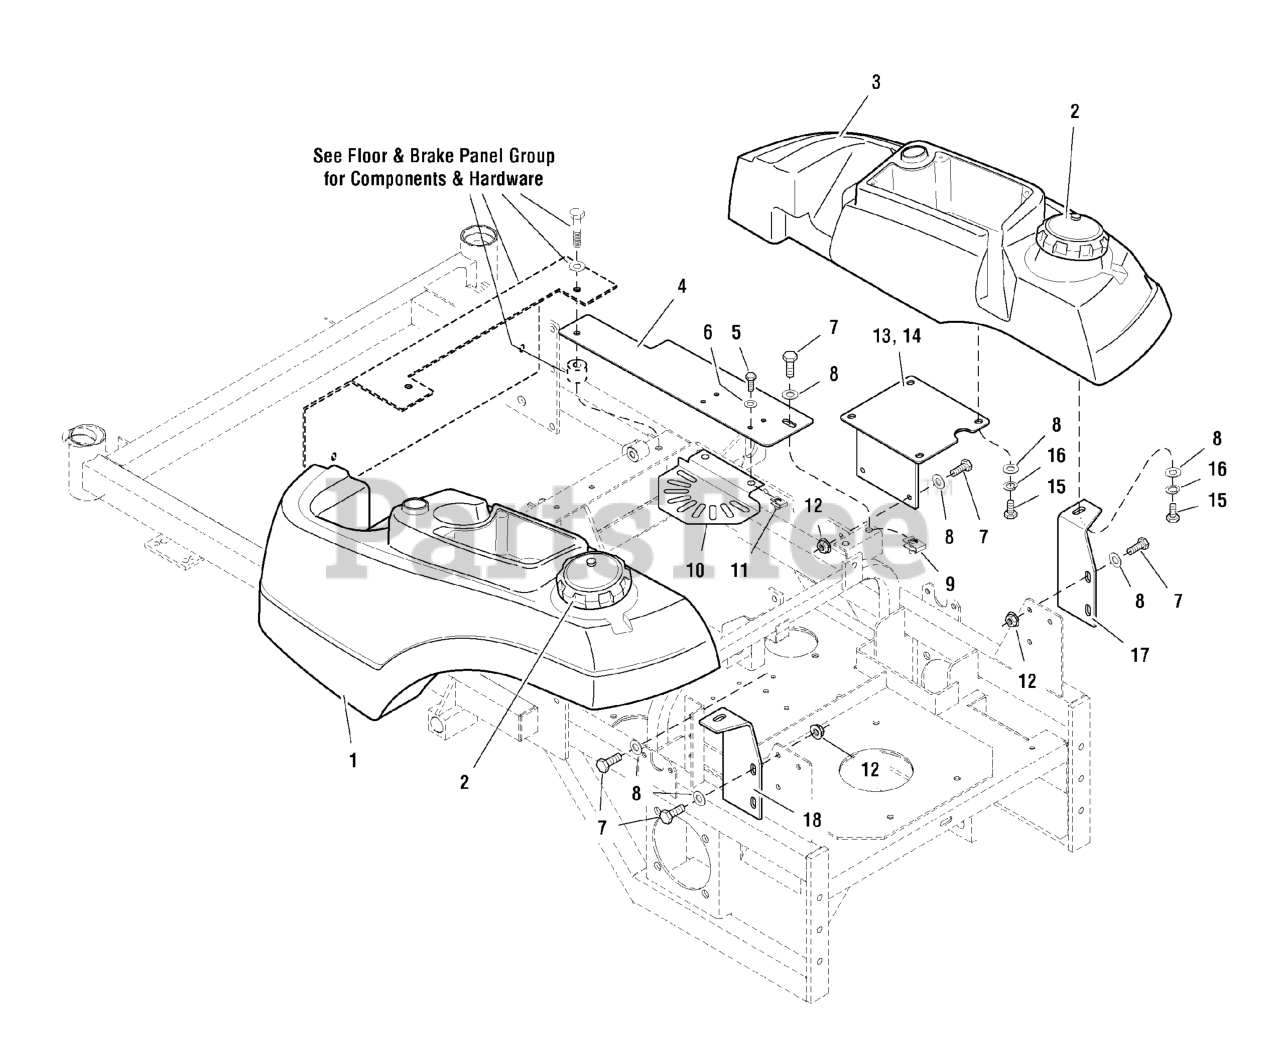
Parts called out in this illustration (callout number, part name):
1	FUEL TANK, 1000Z, LH
1	Filler Neck
2	CAP, FUEL TANK, 3-1/2 NECK
3	FUEL TANK, 1000Z, RH
3	Filler Neck
4	COVER, Fan Shield Mount
5	BOLT, 1/4-20 x 3/4
6	WASHER, 1/4 SAE
7	BOLT, 5/16-18 X 1 GD5 YZ
8	WASHER, 5/16" SAE
9	BODY CLIP, 5/16-18-7GA MATERIAL
10	FAN SHIELD
11	BODY CLIP, 1/4-20
12	NUT, 5/16-18 HEX SERRATED FLANGE (SMALL)
13	FUEL TANK MOUNT-RH
14	FUEL TANK MOUNT-LH
15	BOLT, 5/16-18 X 3/4 GD5
16	WASHER, 5/16 LOCK CZ
17	BRACKET, Fuel Tank Support-RH
18	BRACKET, Fuel Tank Support-LH
